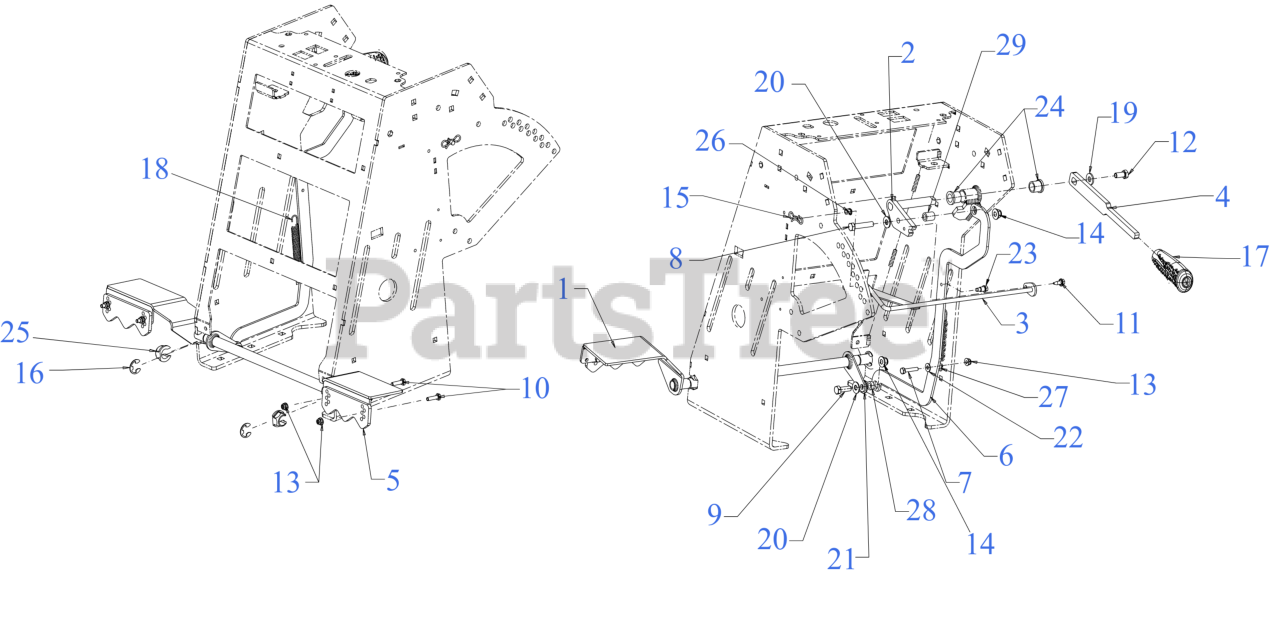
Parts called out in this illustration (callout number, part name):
1	BRAKE ASSEMBLY
2	BRAKE HANDLE PIVOT ASSEMBLY
3	LOCK CONTROL ROD ASSEMBLY
4	BRAKE HANDLE
5	BRAKE WEDGE BRACKET
6	BRAKE CONNECTION PLATE
7	HEX SCREW 1/4-20 x 1.25
8	HEX SCREW 3/8-16 x 1.75 GR5
9	SCREW 3/8-16 x 1 GR5
10	SCREW 1/4-20 X1.00 GR5
11	SCREW 1/4-20X.625
12	SCREW 3/8-16 x .75 GR 5
13	FLANGE LOCK NUT
15	PIN:COTTER
18	EXTENSION SPRING
19	FLAT WASHER .385X.870X.090
20	FLAT WASHER
21	WASHER-.395 x 1.0 x .62
22	FLAT WASHER .271:.630:.065
23	SHOULDER SCREW
24	FLANGE BEARING
25	HEX FLANGE SPLIT BEARING
26	BUSHING .3135ID
27	SPLIT SPACER
28	SPACER-.380 ID x .625 OD x .227
29	SPACER .38 x .625 x .43
